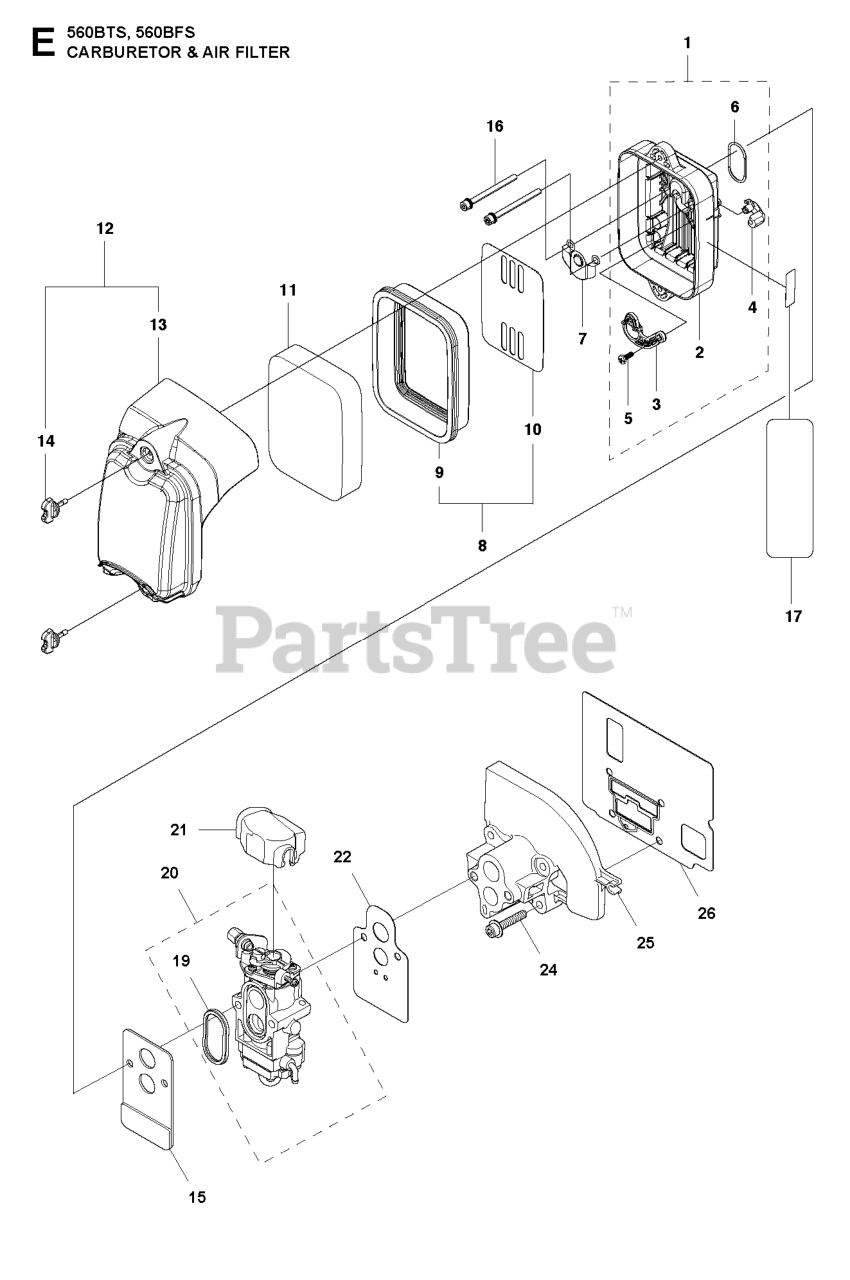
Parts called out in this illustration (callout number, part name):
1	AIR FILTER HOLDER ASSY
2	AIR FILTER HOLDER
3	PLATE
4	LEVER
5	SCREW
6	O-RING
9	PACKING
10	SCREEN
11	AIR FILTER
12	AIR FILTER COVER
13	AIR FILTER COVER
14	KNOB
17	LABEL,CHOKE
19	RING
20	CARBURETOR
